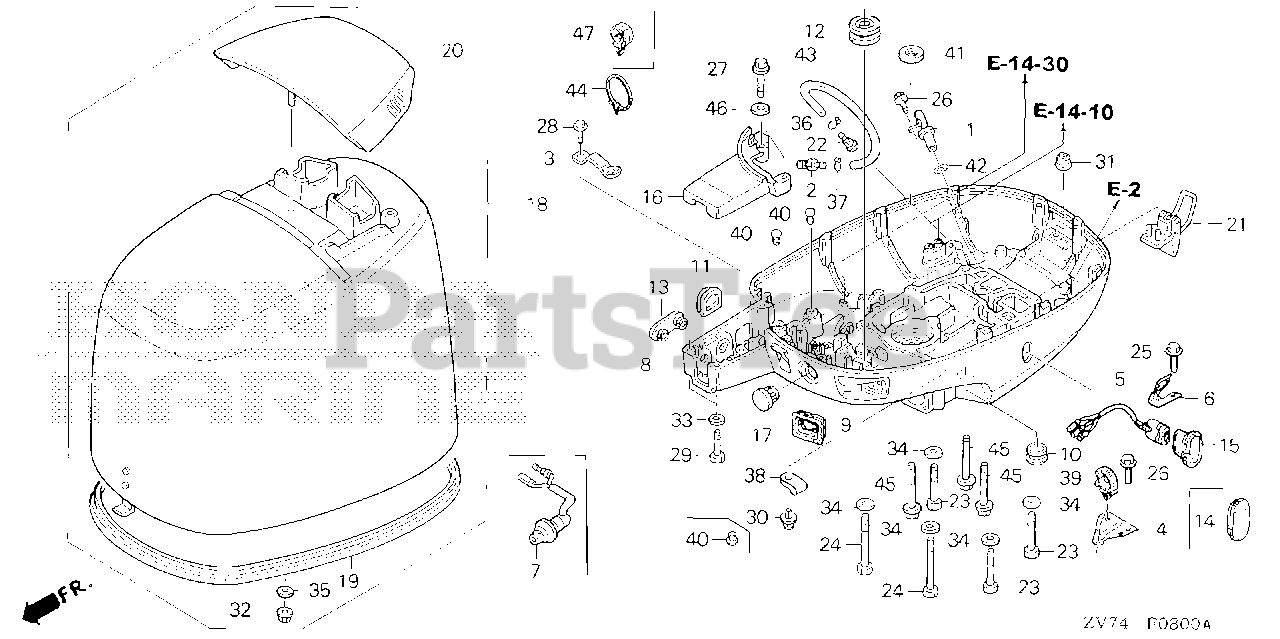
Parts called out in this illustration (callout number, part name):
1	PIPE, OIL LEVEL
2	JOINT, WATER TUBE
3	BRACKET, CABLE CLIP (S)
7	LAMP ASSY., INDICATOR
8	CASE, ENGINE (LOWER) *NH282MU* (OYSTER SILVER METALLIC-U)
9	GROMMET, CASE (LOWER) (B)
10	GROMMET, CASE (LOWER) (C)
12	GROMMET, OIL CASE (E)
13	GROMMET, CASE (LOWER)
14	GROMMET, CASE (LOWER)
16	CASE, SEPARATE *NH282MU* (OYSTER SILVER METALLIC-U)
18	COVER, ENGINE *NH282MU* (OYSTER SILVER METALLIC-U)
19	SEAL, ENGINE COVER
20	HANDLE, TILT *NH282MU* (OYSTER SILVER METALLIC-U)
21	LEVER, FASTENER
22	GROMMET, WATER CHECK
23	BOLT, HEX. (8X55)
24	BOLT, HEX. (8X80)
26	BOLT, FLANGE (6X12) (CT200)
27	BOLT, FLANGE (6X28) (CT200)
28	BOLT, FLANGE (5X10) (CT200)
29	BOLT, HEX. (6X45)
31	NUT, SELF-LOCK (6MM)
32	NUT, U (6MM) (FUSE RASHI)
33	WASHER, PLAIN (6MM)
34	WASHER, PLAIN (8MM)
35	WASHER (6MM)
36	CLIP, TUBE (B8)
37	CLIP, TUBE (B10)
40	PLUG, CHANGE REINFORCEMENT
41	SEAL, WATER (17X26X7)
42	O-RING (11.5X3.5)
43	TUBE, WATER CHECK
45	BOLT, FLANGE (8X70)
46	WASHER, PLAIN (6MM)
47	CLIP, WIRE HARNESS (25MM)
